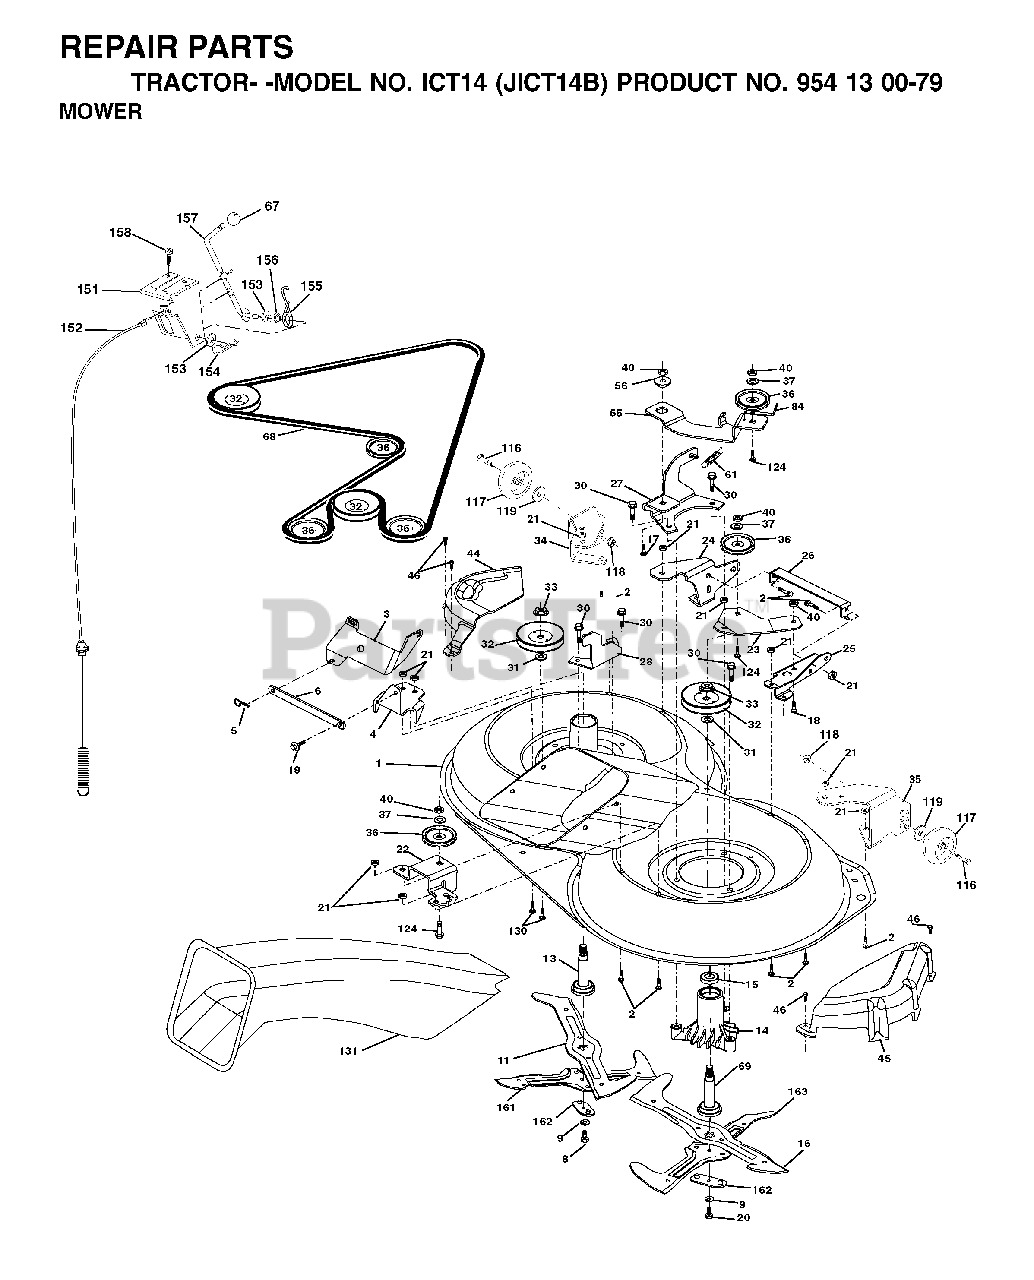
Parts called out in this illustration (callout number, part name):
1	MOWER HOUSING, DECK
2	BOLT
3	BRACKET
5	RETAINER-SPRNG RB
6	BAR SWAY
9	LOCKWASHER
10	WASHER.BLADE
11	BLADE-LH 5PT STAR(CTH130)
13	SHAFT ASM VENT
14	HSG MANDREL
16	BLADE RH 6PT STAR(CTH130)
17	BOLT.3/8-14X1.25
19	BOLT SHD 5/16-18
21	LOCKNUT
24	BRACKET
25	BRACKET
26	BRACE
28	BRACKET
30	SCREW, WASHER HEAD
31	WASHER
32	PULLEY, MANDREL
33	NUT, FLG TOPLOCK 9/16"
36	PULLEY.IDLER.4.25
40	LOCKNUT
45	MANDREL COVER
46	SCREW.1/4-20X5/8
55	ARM IDLER
56	SPACER.RETAINER.MOWER
61	SPRING.TENSION.BELT
67	KNOB T (3/8 HOLE)
68	HEX-BELT
69	SHAFT.ASM.W/LWR.BRG.RH.THREAD
84	KEEPER, BELT IDLER
116	BOLT, SHOULDER
117	WHEEL GAGE DONUT
118	LOCKNUT
119	WASHER
124	BOLT.3/8-16X1.50
131	CHUTE BAGGER
151	BRACKET, CLUTCH CABLE
153	WASHER FLAT 3/8"
154	SPRING RETAINER
155	SPRING RETENTION LEVER
156	SPACER CLUTCH CABLE
157	ROD CLUTCH CABLE 3/8"
158	SCREW
